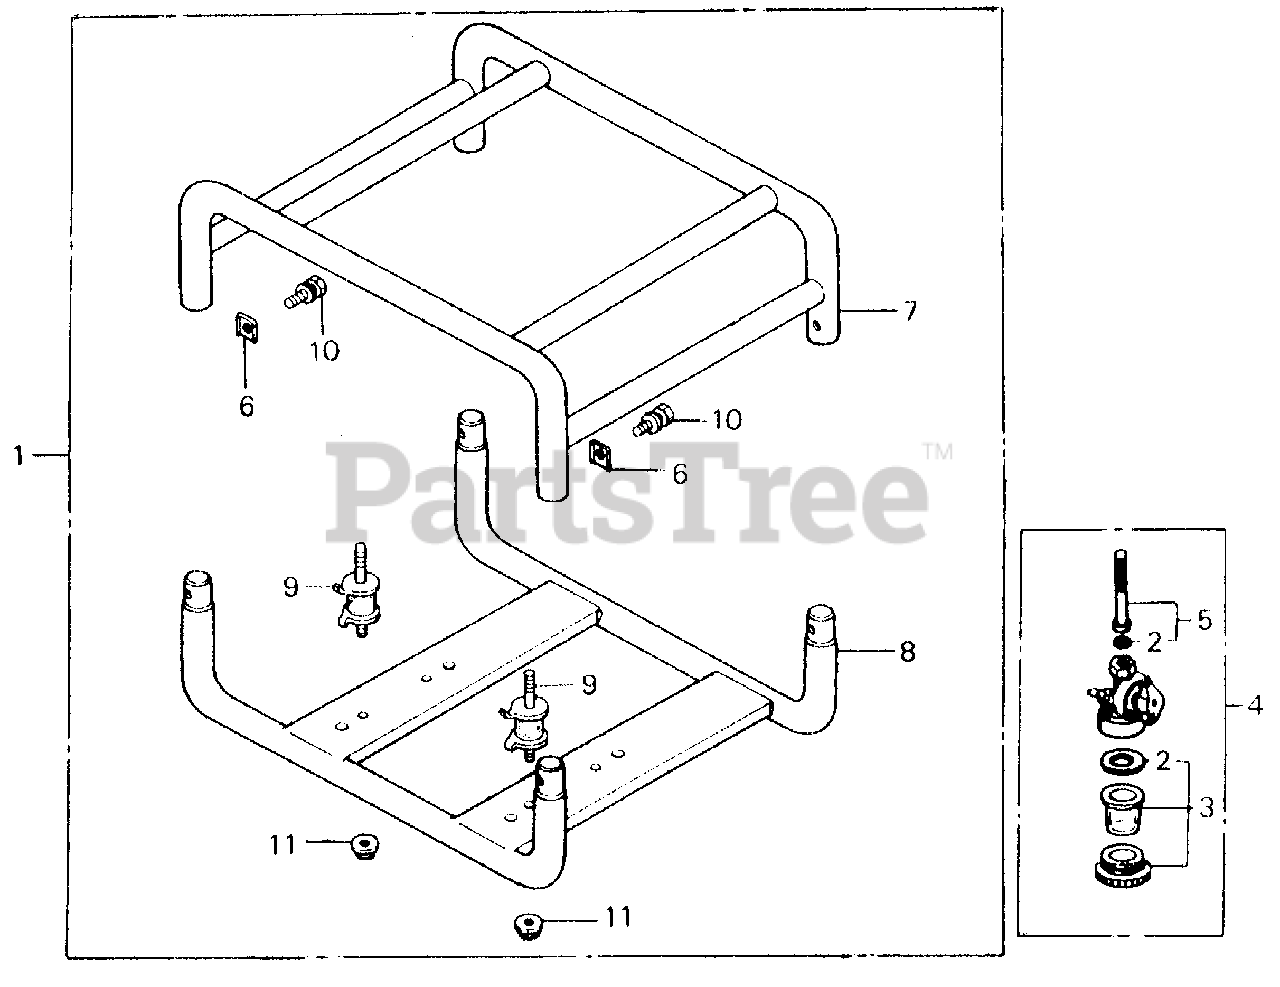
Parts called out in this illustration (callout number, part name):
1	FRAME KIT *NH105* (MAT BLACK)
2	GASKET SET, VALVE
3	CUP SET, FUEL STRAINER
4	PETCOCK ASSY.
5	SCREEN SET
6	PLATE, JOINT
6	WASHER, FRAME JOINT
7	FRAME (UPPER) *NH105* (MAT BLACK)
8	FRAME (LOWER) *NH105* (MAT BLACK)
9	RUBBER, ENGINE MOUNTING
10	BOLT-WASHER (8X16)
11	NUT, FLANGE (8MM)
